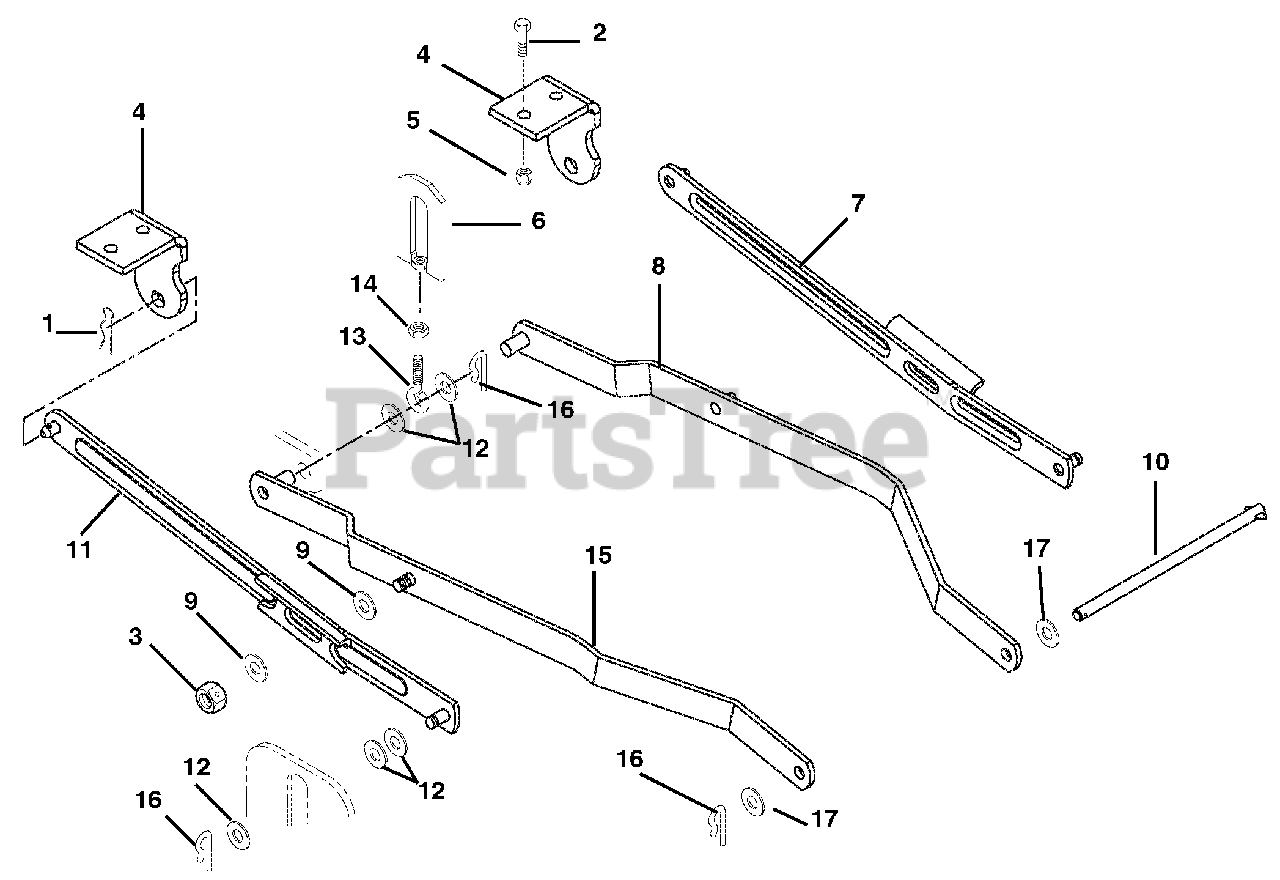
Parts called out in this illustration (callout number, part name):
1	Pin-Hair External .12 x .31 x 2.37
2	Bolt-Screw Hex Flanged Whiz Lock Head .38-16 x .75
3	Nut-Locking-Center .625-11
4	Rear Hanger
5	Nut-Locking-Top-Flange .38-16
6	Link, Adjustment
6	Weldment, Adjustment Link
7	Hanger, Rear Left Hand
8	Arm, Lift Left Hand
9	Washer-Flat-Steel .656 x .31 x .095
11	Hanger, Rear Right Hand
12	Washer-Flat-Steel .531 x 1.25 x .10
14	Nut-Jam .375-16
15	Arm, Lift Right Hand
16	Clip, Spring
17	Washer-Flat-Steel .53 x 1.06 x .095
